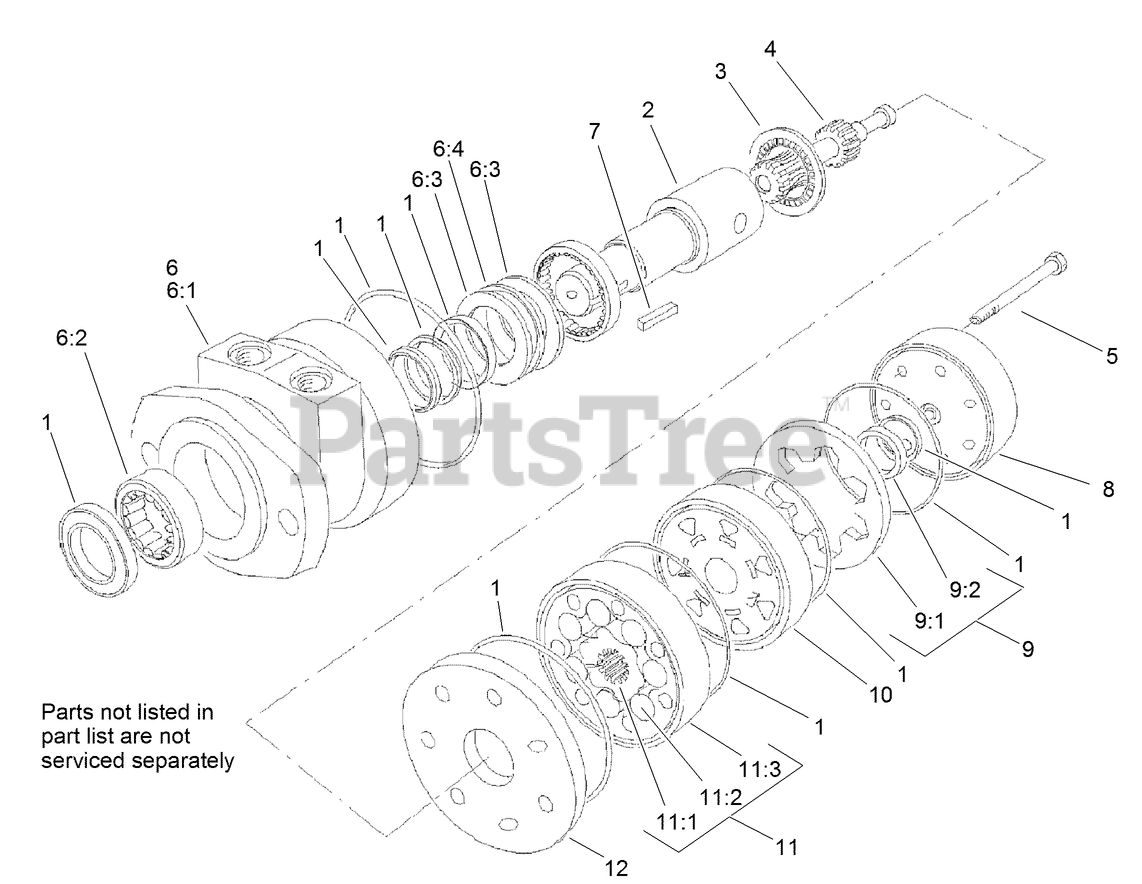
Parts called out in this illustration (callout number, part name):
2	COUPLING SHAFT
3	BEARING-THRUST
4	LINK-DRIVE
5	SCREW-HH
6	HOUSING ASM
6:1	HOUSING
6:2	Bearing
6:3	Washer-Thrust
6:4	Bearing-Thrust
7	KEY-SQUARE
8	END COVER ASM
9:1	Ring-Commutator
9:2	Commutator
10	MANIFOLD
11	ROTOR SET
11:1	Rotor
11:2	Vane
11:3	Stator
12	PLATE-WEAR
